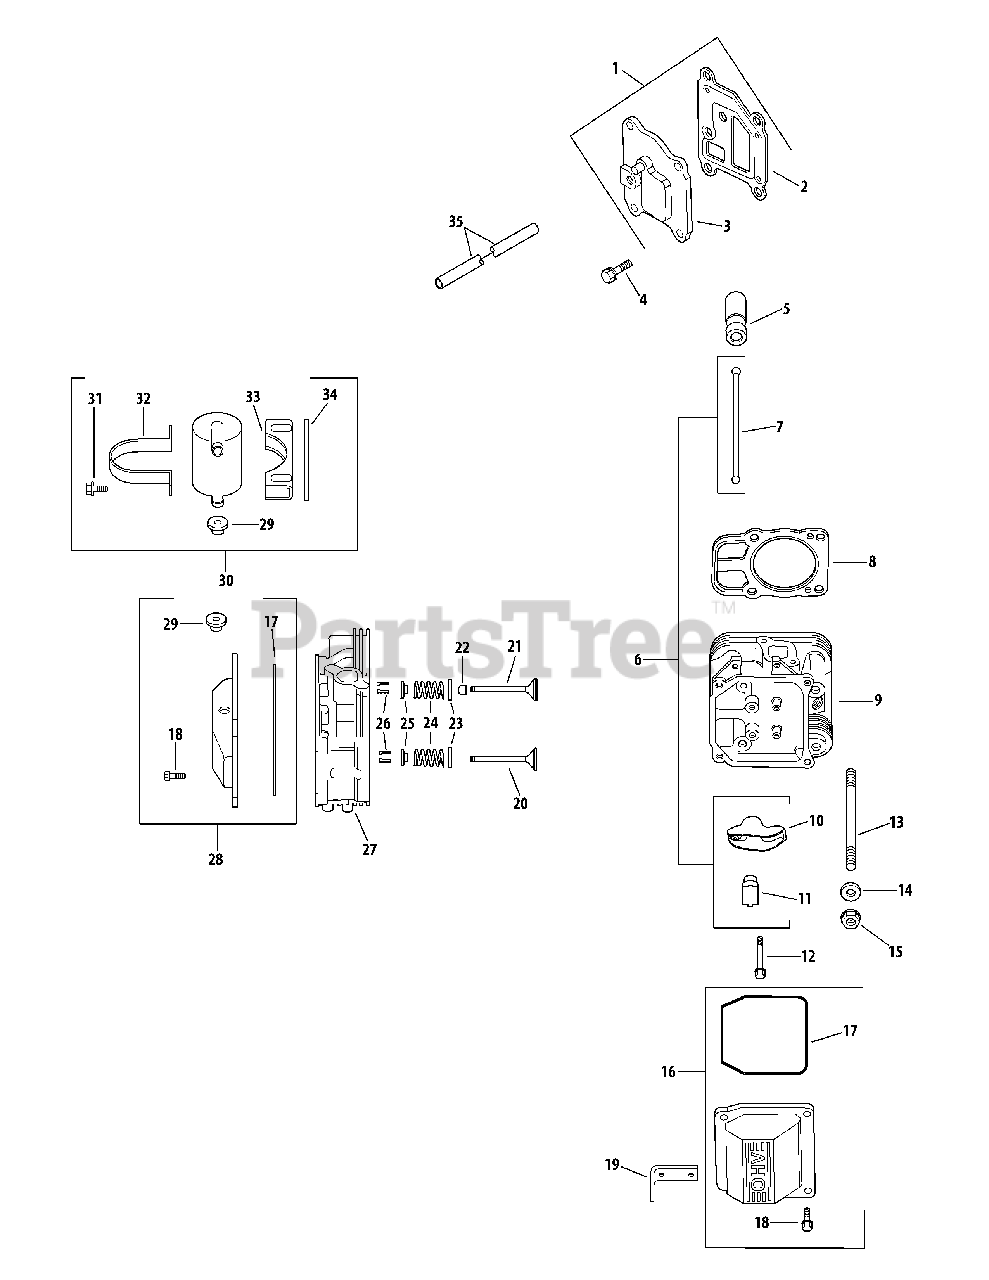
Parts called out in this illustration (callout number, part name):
1	Breather Cover Kit w/ Gasket
3	Breather Cover Kit
4	Flange Screw, M6 x 1.0 x 20
5	Lifter
6	Valve Train Kit
8	Gasket Cylinder Head Gasekt
9	Cylinder Head Assembly
11	Pivot Rocker Arm
12	Flange Screw, M6 x 1.0 x 34
13	Stud, M8 x 1.25
14	Flat Washer, 8.6 mm
15	Flange Nut, M8 x 1.25
16	Valve Cover Kit (Plain) (Inc. 17 & 18)
17	Valve Cover O-Ring
18	Flange Screw, M6 x 1.0 x 30
19	Lifting Strap
20	Valve Exhaust (Standard)
20	Valve Exhaust (.25)
21	Valve Intake (Standard)
21	Valve Intake (.25)
22	Valve Stem Seal
23	Retainer Spring
24	Spring Valve
25	Spring Cap Valve
26	Retainer Kit
27	Cylinder Head Assembly
28	Valve Cover Kit
29	Rubber Grommet
30	Breather Separator Kit
31	Flange Screw, M5 x 0.8 x 16
32	Breather Strap
33	Breather Separator Bracket
35	Breather Hose
